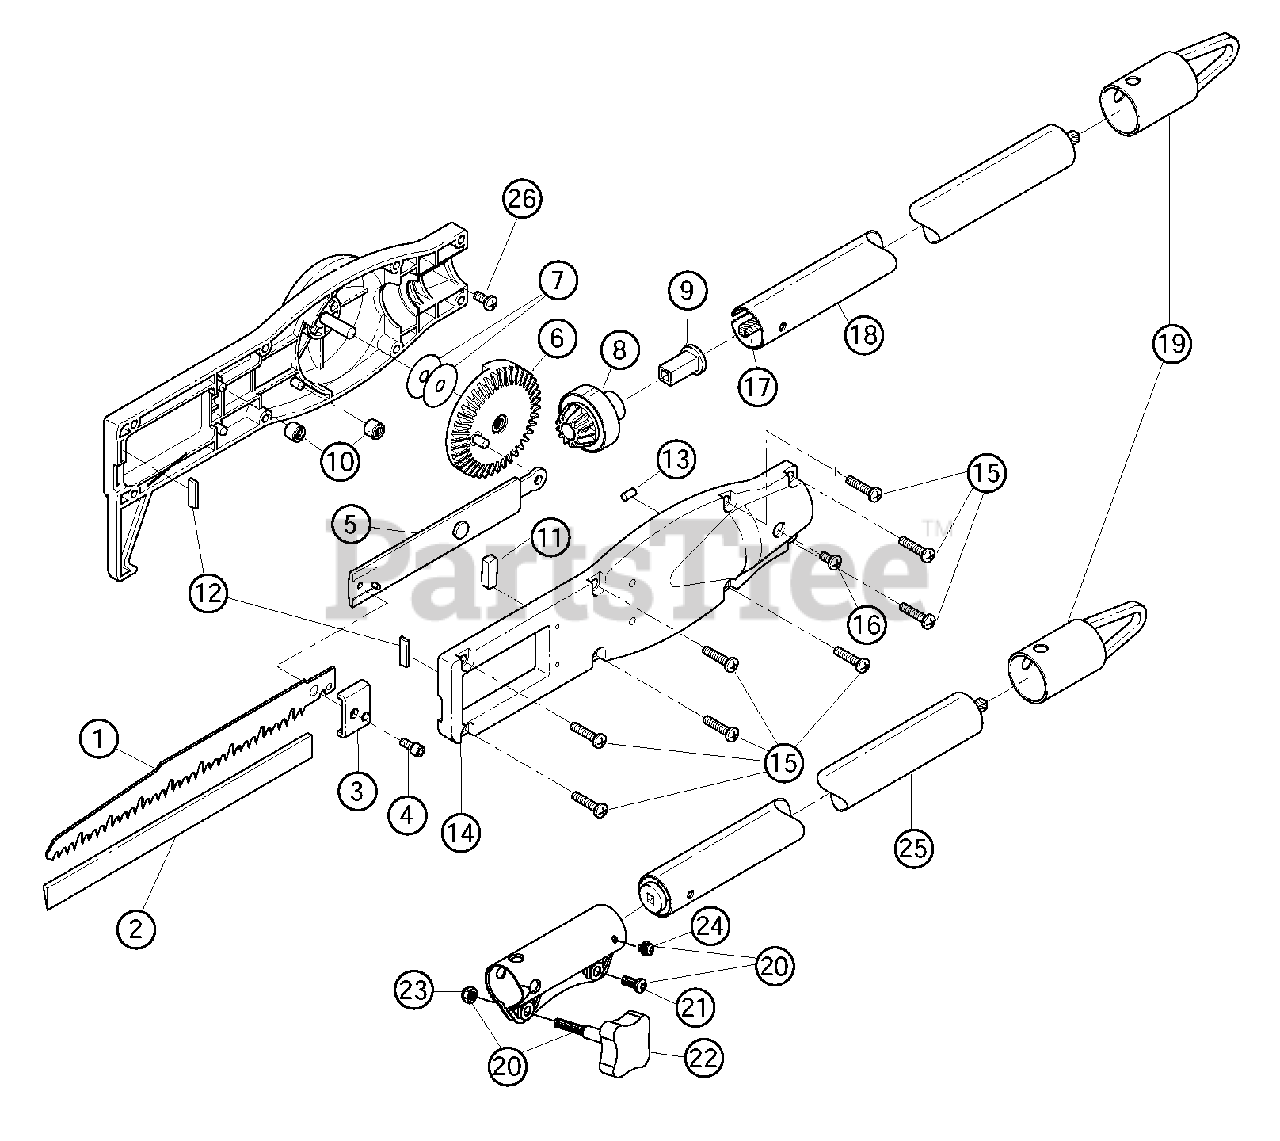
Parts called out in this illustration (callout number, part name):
1	Blade (2 pack)
2	Blade Cover
3	Blade Clamp
4	Blade Clamp Screw & Washer Assembly
5	Arbor Assembly
6	Bevel Gear
8	Pinion Bevel Gear
10	Slide Bushing
12	Slider
13	Rubber Plug
14	Housing set
15	Housing Screw
16	Anti-Rotation Screw
17	Drive Shaft Assembly
18	Drive Shaft Housing Assembly
19	Hanger
20	Coupler
22	Adjustment Knob
23	Knob Retaining Nut
25	Extension Boom and Flex Shaft Assembly
26	Anti-Rotation Screw
